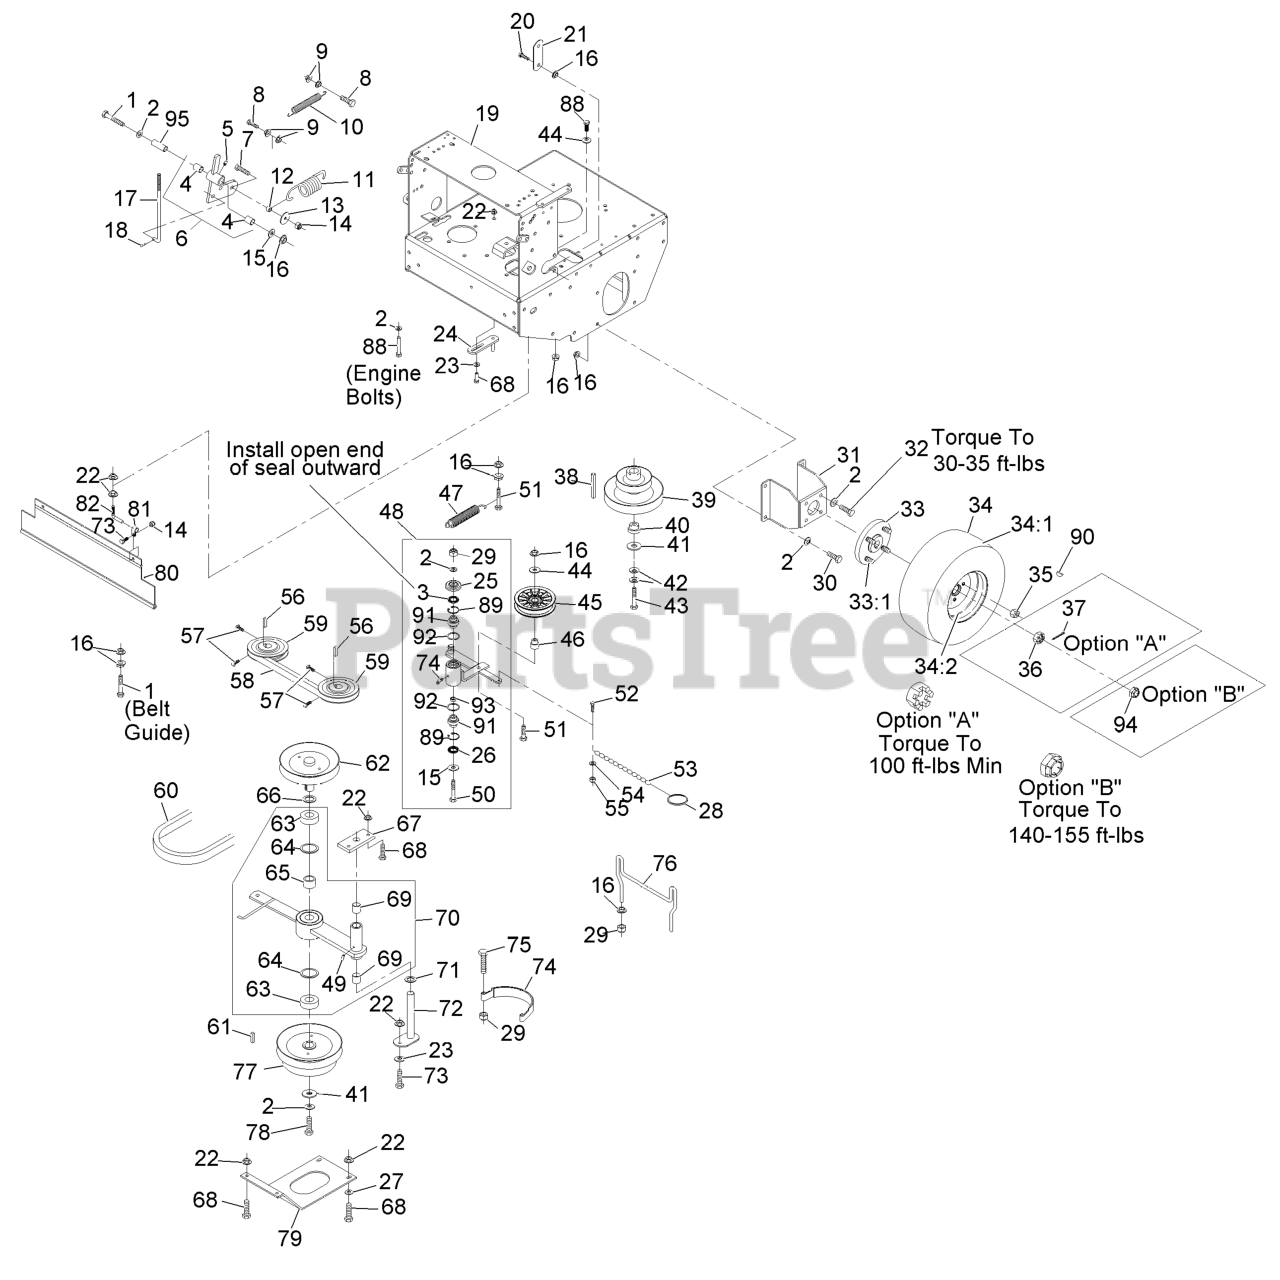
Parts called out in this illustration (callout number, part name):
1	SCREW-HH
2	WASHER-BELLEVILLE
3	SEAL-LIP, SINGLE
4	SLEEVE-BEARING
5	FITTING-GREASE
6	ASM,PIVOT W/BUSHINGS
7	SCREW-HH
8	SCREW-HH
10	SPRING,EXTENSION
11	SPRING,EXTENSION
12	SPACER,CLUTCH ANCHOR
14	NUT-LOCK, NI
15	WASHER-FLAT
16	NUT-HHF, WHIZ
17	LINKAGE,LOWER
18	PIN-COTTER
19	KIT,TTHP ENG DECK
20	SCREW-HH
21	ARM-LIFT, DECK
23	WASHER-SPRING
24	GUIDE-BELT
25	GUARD-TOP
26	SEAL-LIP, DOUBLE
27	WASHER-FLAT
28	RING-SPLIT
29	NUT-LOCK, NI
30	SCREW-HH
31	WLD,MOTOR MOUNT 36
32	SCREW-HH
33:1	STUD-WHEEL
34	WHEEL AND TIRE ASM
34:1	TIRE-TURFMASTER
34:2	RIM-WHEEL
35	NUT-LUG
36	NUT-HEX, SLOTTED
37	PIN-COTTER
38	KEY,MACH 1/4X1/4X2-5/8
39	SHEAVE, DRIVE
40	BUSHING,CLUTCH KEEPER
42	WASHER-SPRING
43	SCREW-HH
44	WASHER-FLAT
45	PULLEY-IDLER, FLAT
46	BUSHING-IDLER
48	KIT,PUMP IDLER ARM TTHP
49	FITTING-GREASE
50	SCREW-HH
51	SCREW-HH
52	SCREW-HSH
53	CHAIN-LINK, TWIST
54	WASHER-FLAT
55	NUT-LOCK, NI
57	SCREW-SET
58	BELT,COG A 50.55
59	SHEAVE ASM
60	BELT,B-38.0
62	SHEAVE, W/ SHAFT
63	BEARING,CLUTCH SHAFT
64	RING-SNAP
65	SPACER,CLUTCH BEARING
66	WASHER-SPACER
67	PLATE-CLUTCH PIVOT
68	SCREW-HH
69	SLEEVE,BEARING
70	ASM,CLUTCH ARM W/BEARING
71	WASHER-SPACER
72	WLD,PIN PIVOT
73	SCREW-HH
74	BAND,BRAKE BLADE
75	SCREW-HH
76	GUIDE,BELT (PLTD)
77	SHEAVE,6.13 W/HUB
78	SCRW,CAP HH
79	PLATE-GUARD
80	SHIELD-DRAG
81	CLIP-LOOM
82	MOUNT,DRAG SHIELD
88	SCREW-HH
89	RING-SNAP
90	KEY-WOODRUFF
91	BEARING-SPHERICAL
94	NUT-LOCK
95	BUSHING
